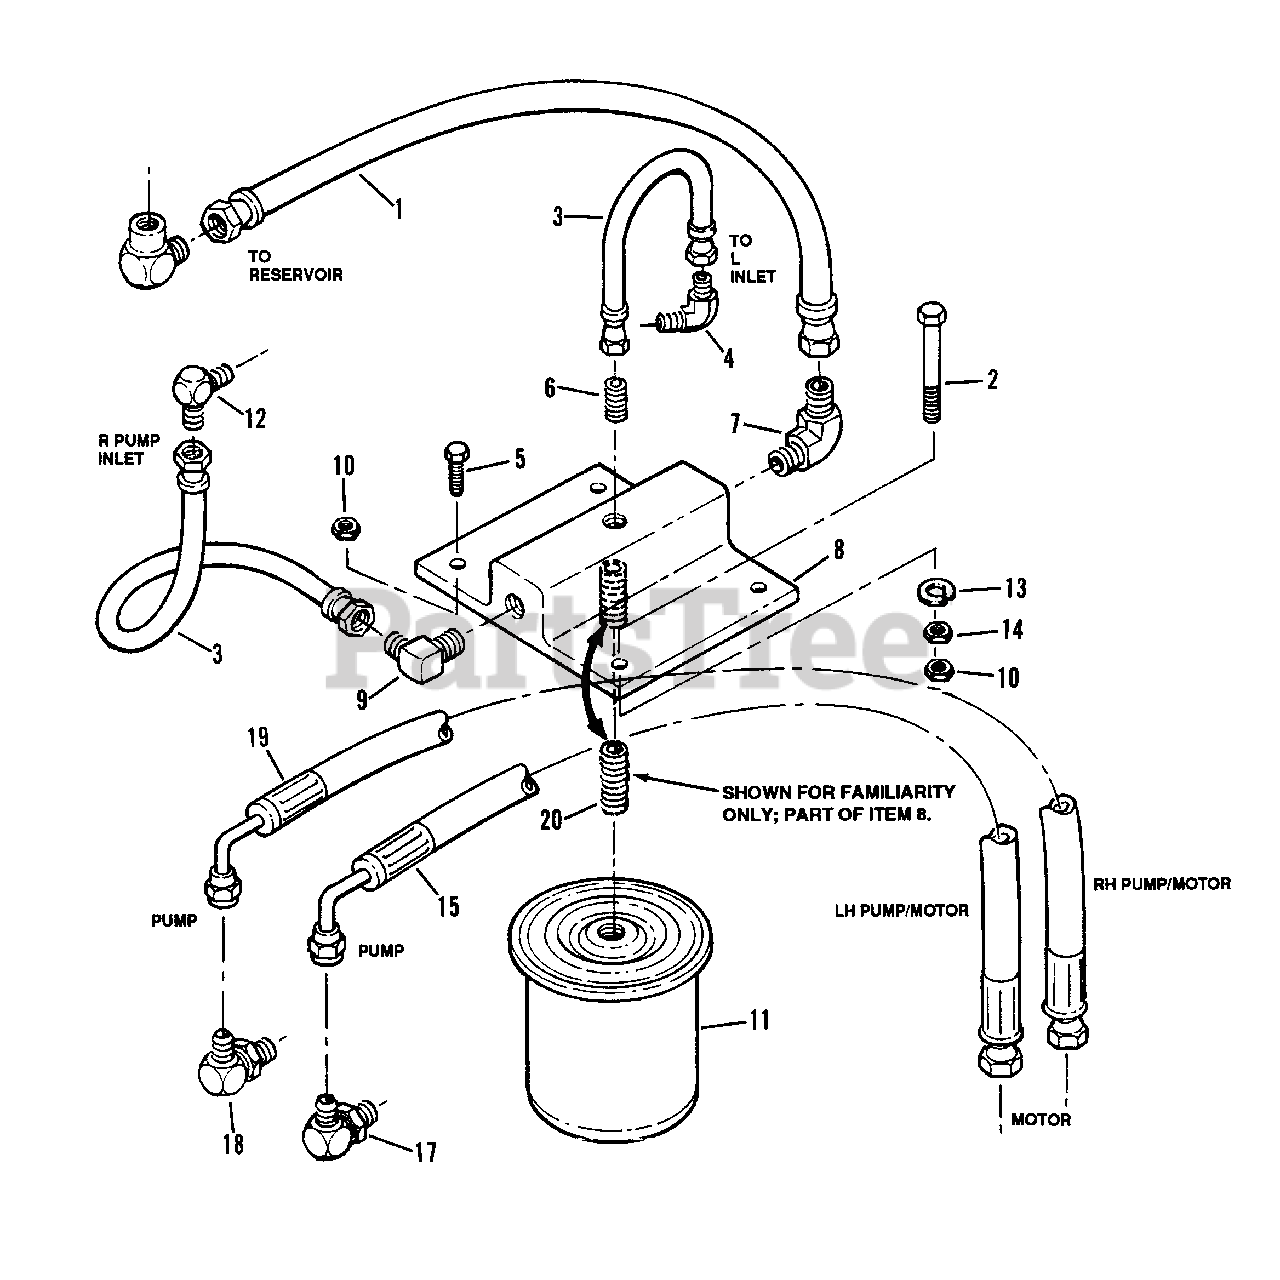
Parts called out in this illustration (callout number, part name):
1	16" HOSE, 1/2"
2	SCREW, 3/8-16 x 3 1/2"
3	9" HOSE
4	FITTING, 90 Degree with "O" Ring
5	SCREW, 3/8-16 x 1"
6	FITTING, Straight
7	FITTING, 90 Degree
8	OIL FILTER MOUNT
9	FITTING, 45 Degree
10	NUT, 3/8-16 Nyloc
11	OIL FILTER
12	FITTING, 90 Degree
13	WASHER, 3/8 Split Lock
14	NUT, 3/8-16 Hex
15	HOSE, PUMP/MOTOR, Left Hand
17	FITTING, 45 Degree with "O" Ring
18	FITTING, 90 Degree with "O" Ring
19	HOSE, PUMP/MOTOR, Right Hand
20	FITTING, Straight 1", #12 Thread
